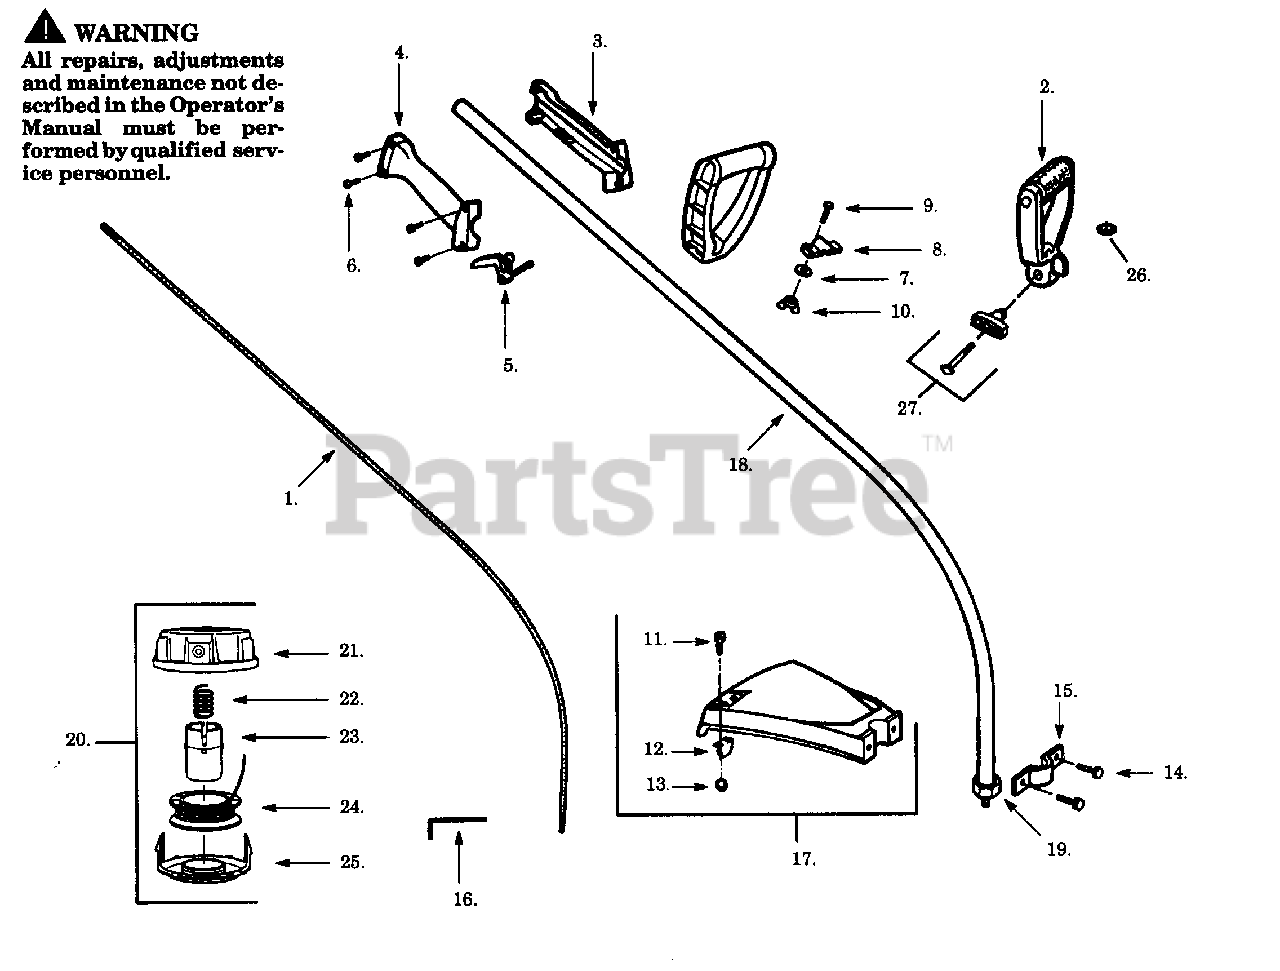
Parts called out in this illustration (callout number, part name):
1	Drive Shaft
3	Throttle Hsg. (Left)
4	Throttle Hsg. (Right)
5	Throttle Lever
12	Line Limiter
13	Locknut
14	Screw
15	Bracket Shield
16	Hex Wrench (5/32)
17	Shield Kit Ass'y.
18	Drive Shaft Hsg.
19	Dust Cup
20	Cutting Head Ass'y. (Inc. 21-25)
21	Hub Ass'y.
23	Release Button
24	Spool w/Line
27	"T" Handle Ass'y.
